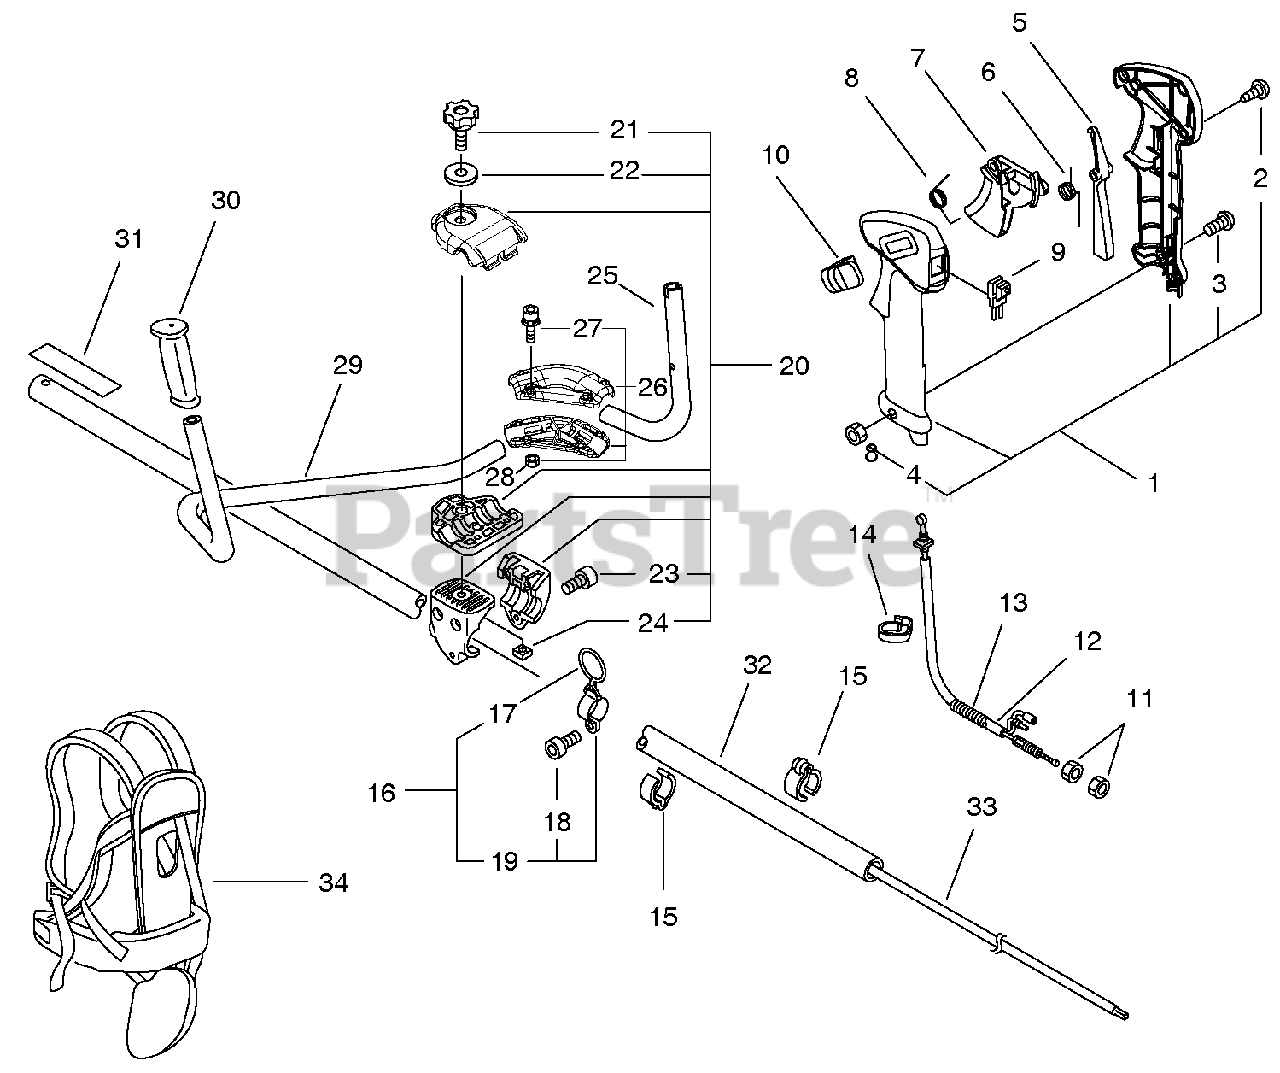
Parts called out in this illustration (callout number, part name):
1	CONTROL HANDLE ASSY
2	SCREW - 4X16
3	SCREW - 5X30
5	LEVER, TRIGGER LOCKOUT
6	SPRING, LOCKOUT LEVER
7	TRIGGER, THROTTLE
8	SPRING, TRIGGER
9	IGNITION SWITCH ASSY
10	LOCK, THROTTLE
12	CABLE, THROTTLE
13	TUBE
16	HANGER ASSY
18	SCREW - 5X12
19	CLAMP
20	HANDLE BRACKET KIT
21	THUMBSCREW
22	WASHER - 8
23	SCREW - 5X30
25	HANDLE, FRONT - RIGHT
26	HANDLE BRACKET KIT
27	SCREW - 5X22
29	HANDLE, FRONT - LEFT
30	GRIP, HANDLE
31	LABEL - CAUTION
32	PIPE, MAIN
33	DRIVESHAFT - SOLID
34	HARNESS ASSY
